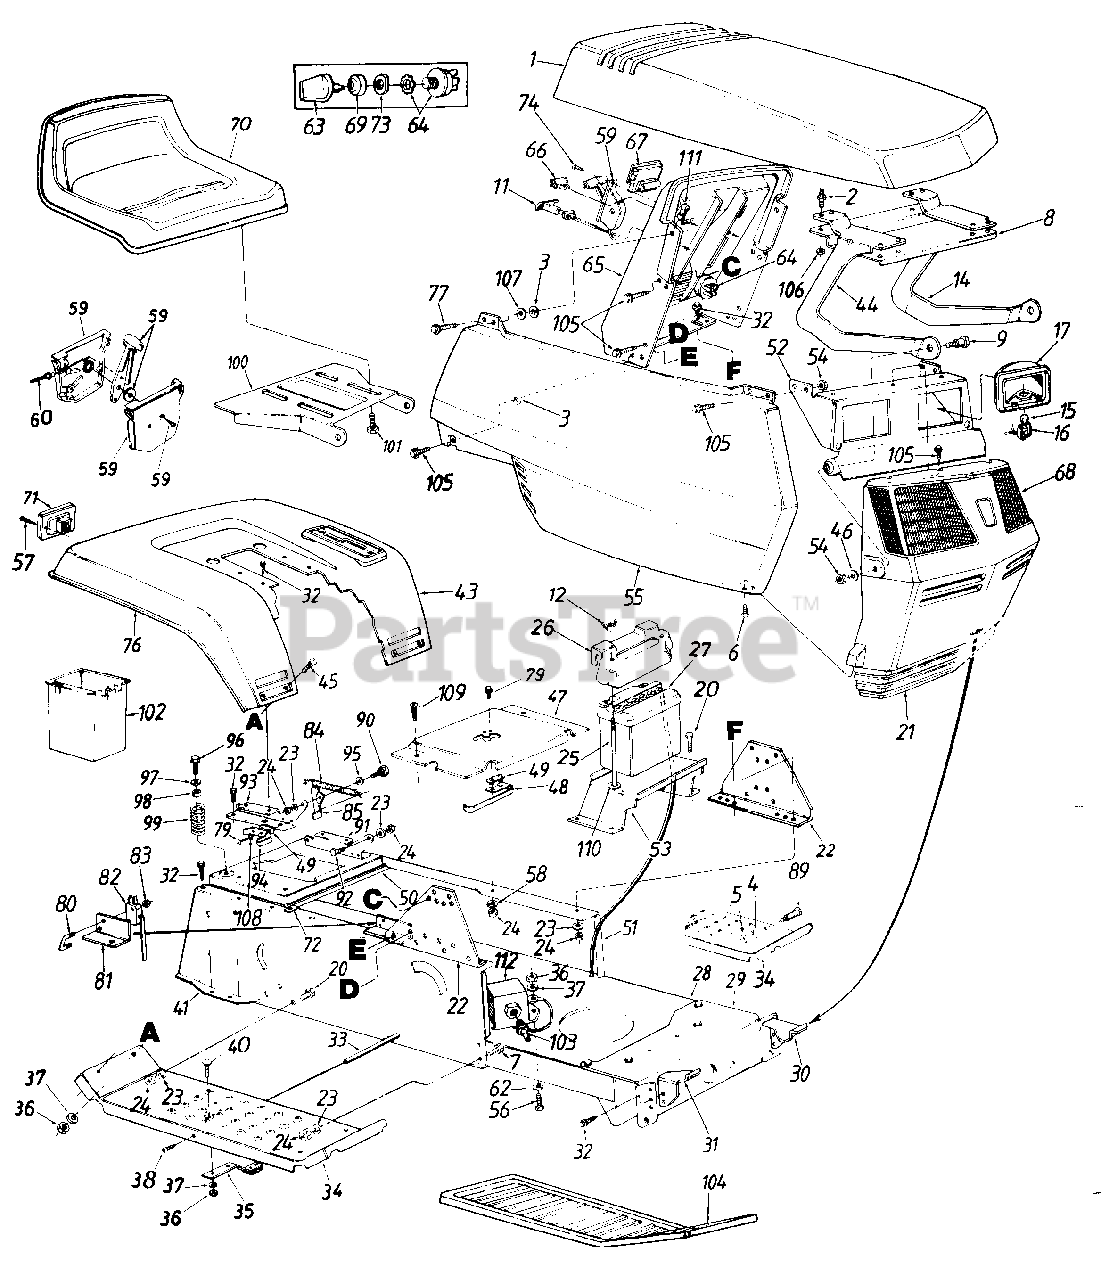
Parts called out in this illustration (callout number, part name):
2	Double Ended Stud 1/4-20 Thd.
3	Pushnut Fastener
4	L-Wash. 3/8" I.D.
5	Hex Nut 3/8-16 Thd.
6	Truss Mach. B-Tap Scr. #10 x .5" Lg.
7	Truss Hd. Scr. 5/16-18 x 1.0" Lg.
8	Hood Reinforcement
9	Shld. Bolt .437" Dia.
11	Choke Control 48" Lg.
12	Wing Nut 1/4-20 Thd.-Plastic
14	Hood Hinge-L.H.
15	Lamp
16	Twist Lock-Lamp Socket
17	Headlight Housing
20	Hex Bolt 5/16-18 x .75" Lg.
21	Grille
22	Dash Support Bracket
23	L-Wash. 5/16" I.D.
24	Hex Nut 5/16-18 Thd.
25	Battery Hold Down Rod
26	Battery Cover
27	12 Volt Battery
28	Lower Frame
29	Front Pivot Brk't.
30	Grille Mount Brk't.-L.H.
31	Grille Mount Brk't.-R.H.
32	Hex Wash. Hd. AB-Tap Scr. 5/16 x .75" Lg.
33	Running Board Rod
34	Running Board
35	Blade Brake Ass'y.
36	Hex Nut 1/4-20 Thd.
37	L-Wash. 1/4" I.D.*
38	Truss Mach. Scr. 5/16-18 x .75" Lg.
40	Carr. Bolt 1/4-20 x .62"
45	Carriage Bolt 1/4-20 x .50" Lg.
46	Fl-Wash..328" I.D. x.68" O.D.
47	Transmission Panel
48	Reverse Safety Switch
49	Insulator Nut Plate
50	Hitch Plate
54	Hex Cent. L-Nut 5/16-18 Thd.
55	Side Cover-R.H.
56	Hex Bolt 1/4-20 x 5/8" Lg. (Grade 5)
57	Truss Hd. AB-Tap Scr. #6 x .62" Lg.
58	Ext. L-Wash. 5/16" I.D.
59	Throttle Control Box Ass'y.
60	Throttle Control Wire 35"
62	Internal Lock Washer
63	Ignition Key
64	Ignition Switch
65	Dash Panel
66	Light Switch
67	Ammeter
68	Lens-L.H.
69	Ignition Switch Cap
70	Seat Ass'y.
71	Taillight
72	Speed Nut #10Z
73	Ignition Switch Nut
74	Truss Mach. AB-Tap Scr. #10 x .5" Lg.
76	Trim Strip-81"
77	Hex Wash. Hd. Tap Scr. 1/4 x.75" Lg.
79	Hex Wash. Hd. AB-Tap Scr. #8 x .50" Lg.
80	Switch Screw
81	Switch Bracket
82	Switch
83	Hex L-Nut #4-40 Thd.
84	Ext. Spring 5.31" Lg.
85	Seat Lift Brkt.
89	Shoulder Bolt
90	Shld. Bolt .437" Dia. x .268"
91	Seat Pivot Brkt. Support-L.H.
92	Shld. Bolt .437" Dia. x .162"
93	Seat Pivot Brkt. Support-R.H.
94	Spring Switch
95	Spr.-Wash. .445" I.D.
96	Hex Wash. Hd. Tap Scr. 5/16-18 x 1" Lg.
97	Fl-Wash..344" I.D.
98	Bushing
99	Compression Spring
100	Seat Pivot Bracket
101	Hex Tap Scr. 3/8-16 x .75"
102	Utility Box
103	Barb Fitting
104	Foot Pad-L.H.
105	Hex Tap Scr. 1/4-20 x .5" Lg.
106	Hex Lock Nut 1/4-20 Thd.
107	Fl-Wash. .27" I.D. x .948" O.D.
108	Fiber Washer
109	Truss Mach. Tap Scr. #10 x .5" Lg.
110	Pushnut Fastener
111	Speed Nut 1/4-20 Thd.
112	Fuel Pump
